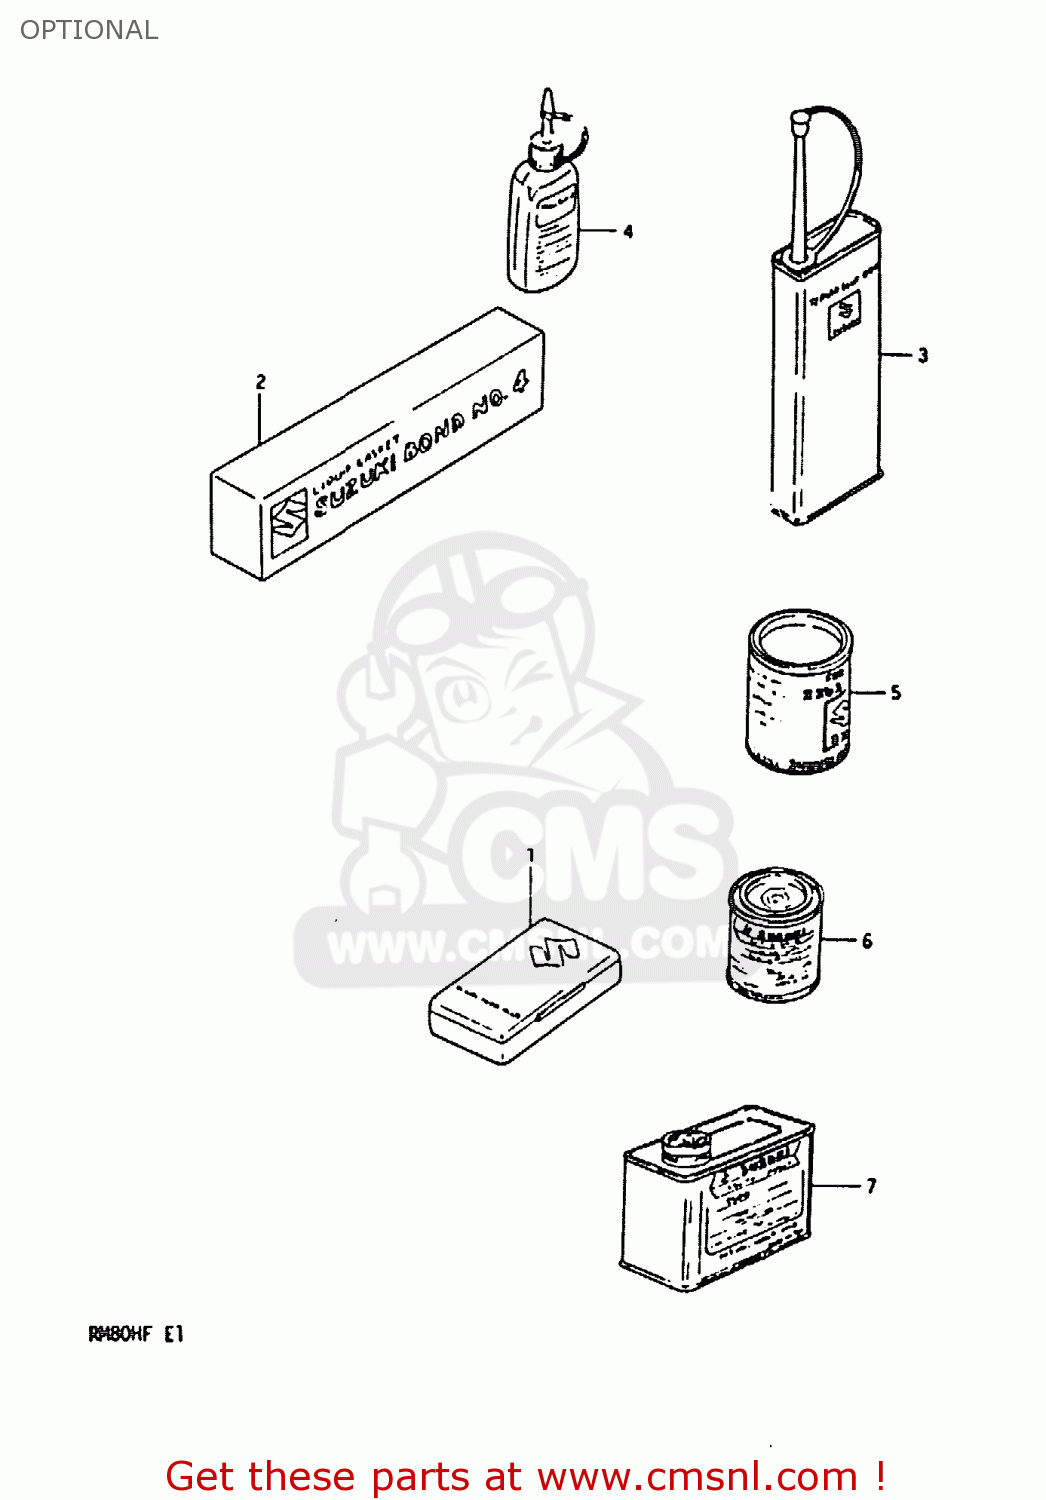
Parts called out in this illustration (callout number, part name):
1	TUBE REPARING TOOL
2	BOND 1104
3	THREAD LOCK NO.1401 CLEAR 200G
4	THREAD LOCK NO
5	GREASE(C)EP2 LITHIUM 150G
6	PAINT,BLACK
7	PAINT (MEDIUM GOLD)
